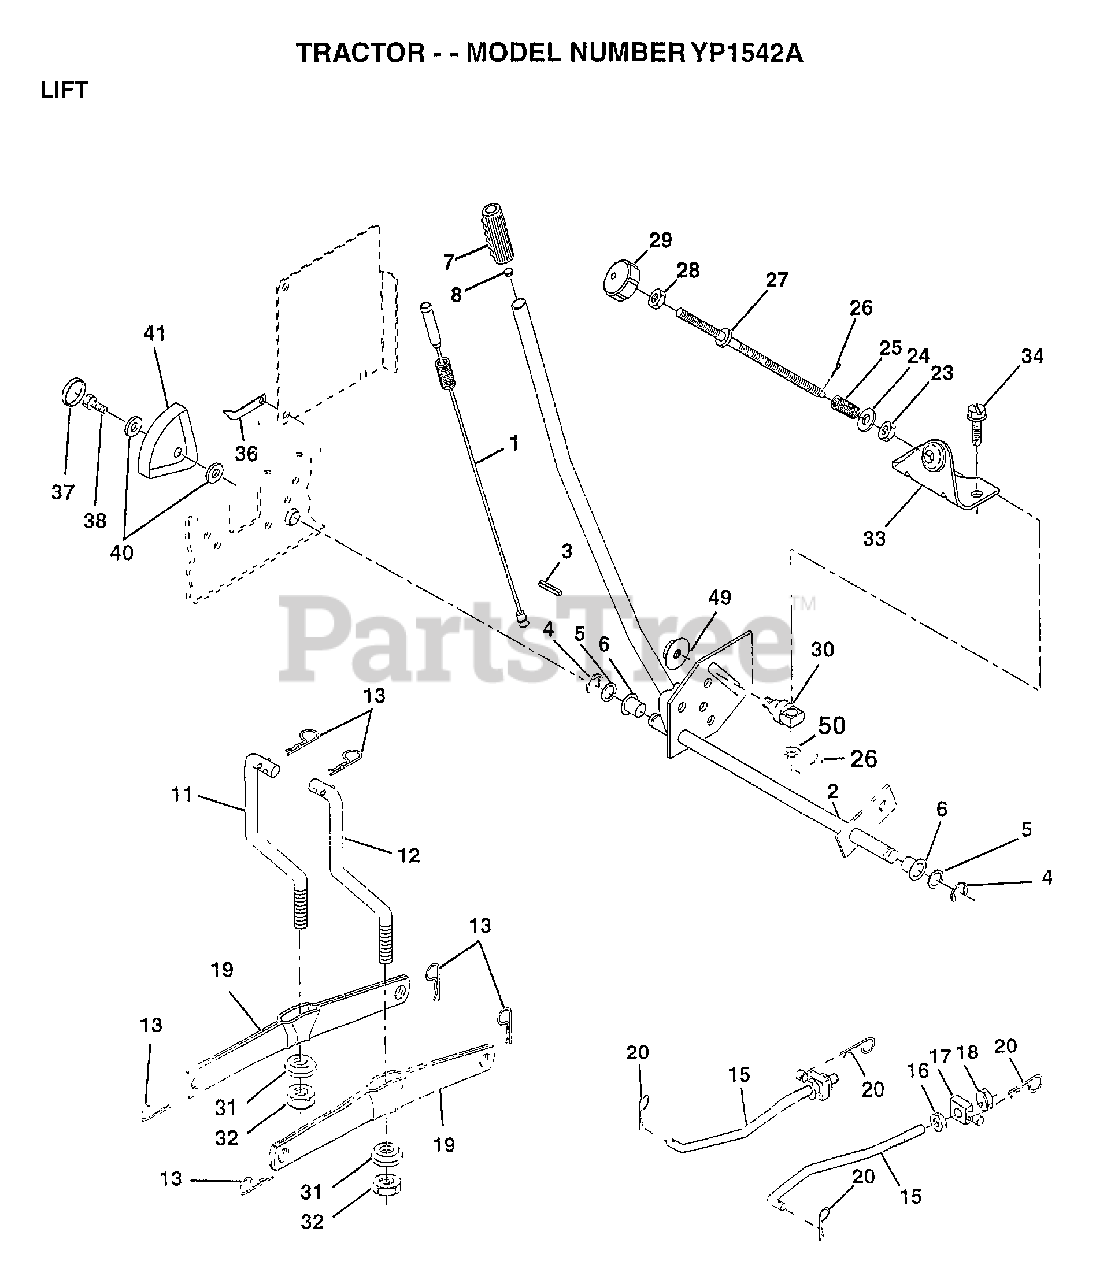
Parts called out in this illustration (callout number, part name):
1	WIRE ASM W.SPRING
2	SHAFT ASM LFT LH
3	PIN GROOVE
5	WASHER
6	NYLON BEARING
7	GRIP HANDLE
15	LINK.FRONT
16	NUT
17	TRUNION
18	NUT.LK.W/WSH.1/2.
19	ARM SUSP REAR
20	RETAINER.SPRING
23	NUT T
24	WASHER
25	SPRING T
28	NUT
29	KNOB INF 3/8-16
30	TRUNNION
31	BEARING PVT LH
32	NUT.CROWNLOCK.3/8
33	BRACKET STOP INF
34	SCREW LT
36	POINTER-INDICAT
37	"PLUG,HOLE"
38	SCREW
40	WASHER
41	HEIGHT INDICATOR
49	NUT.HXFLG.LOCK.
50	NUT PUSH M
